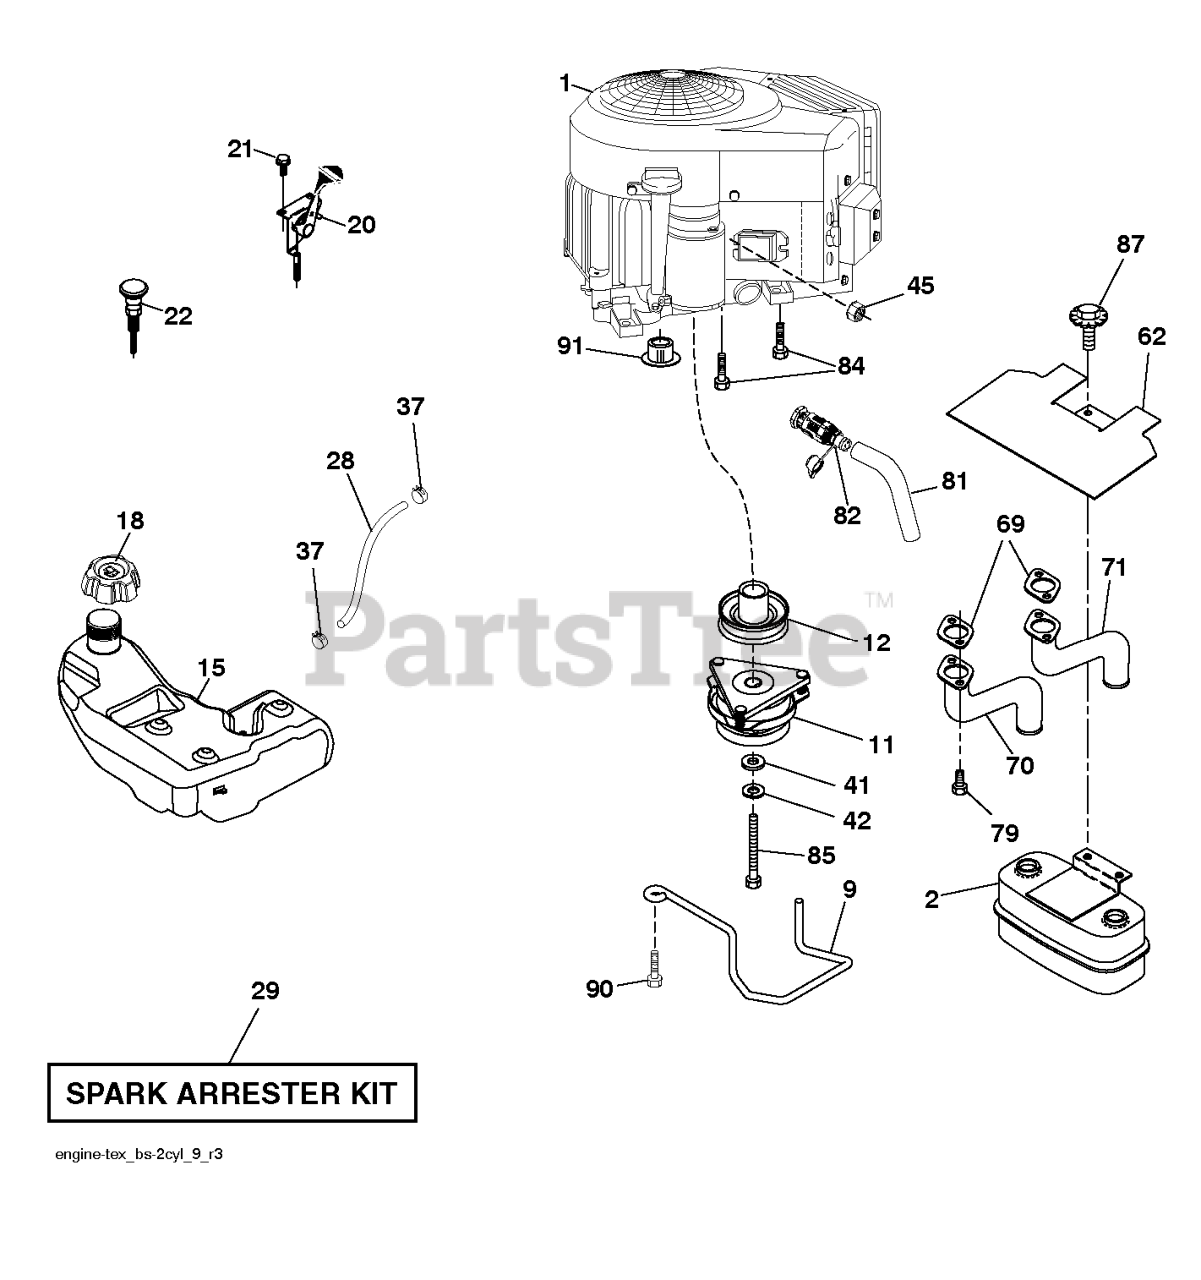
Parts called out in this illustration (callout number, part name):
2	MUFFLER.TWIN.CYL.LOW.TONE
9	KEEPER.BELT.ENGINE.4.2
11	CLUTCH.ELECTRIC.LT.48"*
12	PULLEY.ENGINE.TUFFTORQ
15	RP_TANK.ASSY.3.GAL.EPA
18	CAP.ASM.FL.RITCH.3"E10.SYM.498
20	THROTTLE CABLE
21	SCREW.#10 X 0.750.BOS
22	CONTROL.CHOKE.ERGO.PUSH-IN.BLA
28	LINE.FUEL.64"REAR.EMIS
29	KIT.SPARK ARRESTOR 794945 B&S
37	HOSE CLAMP
42	LOCKWASHER
45	NUT
62	SHIELD.HEAT.MUFFLER
69	GASKET.MUFFLER
70	RP.EXHAUST.TUBE.LH.BS/TWIN
71	EXHAUST.TUBE.RH.BS/TWIN
79	SCREW.SOCKET.HEAD.5/16-18
81	TUBE, DRAIN OIL ASM.
82	VALUE.OIL.DRAIN
84	SCREW.3/8-16
85	BOLT HEX 7/16-20X4-1/4"
87	BOLT.5/16-18UNCX3/4 W/SEMS.BLK
90	SCREW 3/8-16X1
91	BUSHING.1.375OD
